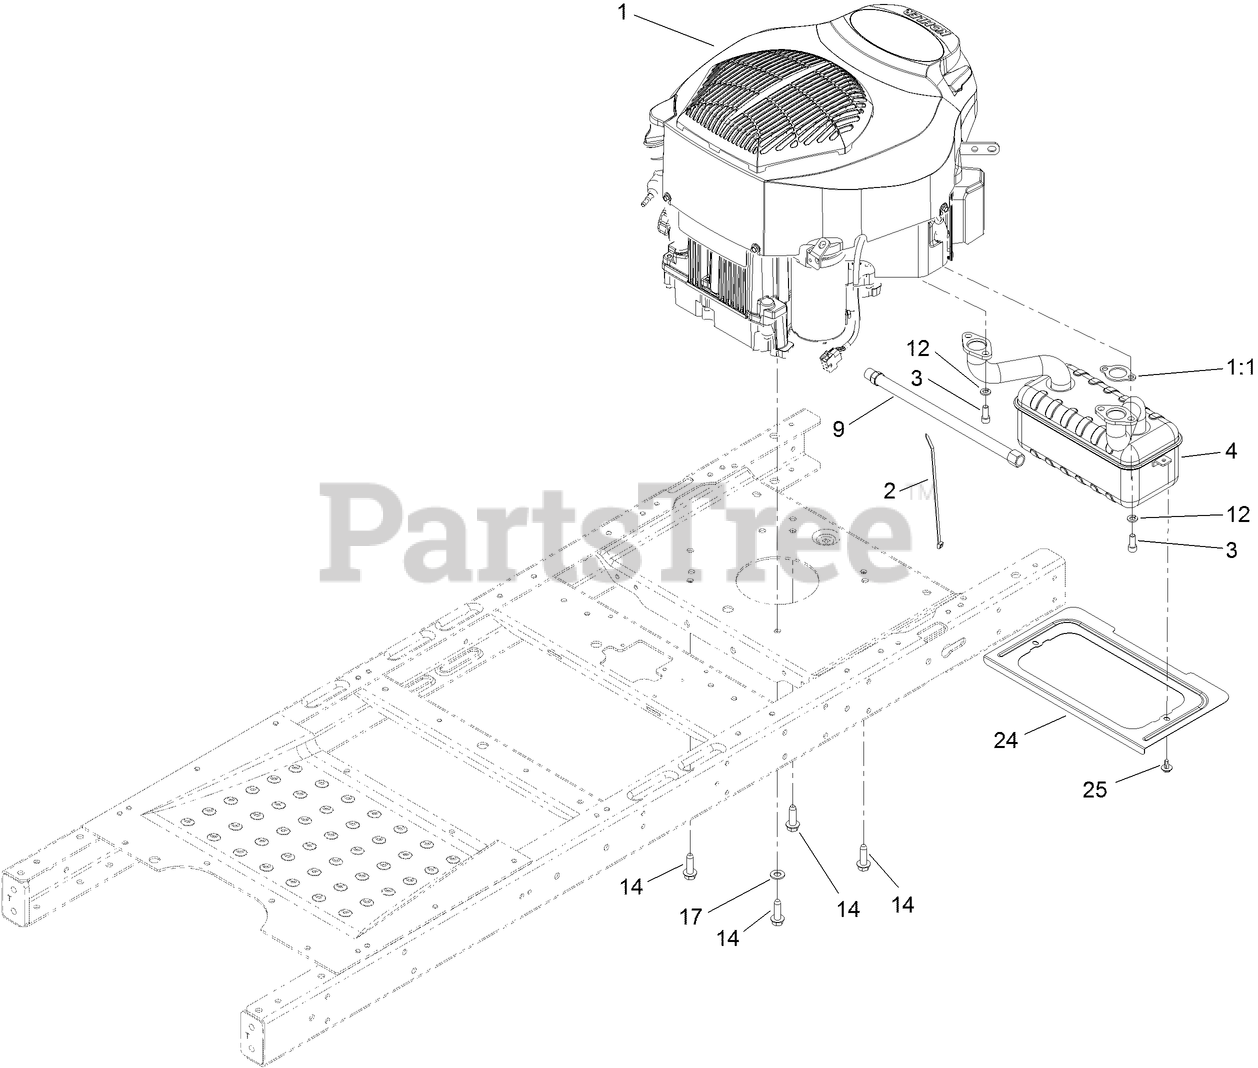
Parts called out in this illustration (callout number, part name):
1	ENGINE-KOHLER 22 HP 7000 SERIES CARB
1:1	GASKET-EXHAUST
2	TIE-CABLE
3	SCREW-HSH
4	MUFFLER
9	HOSE-DRAIN, OIL
12	WASHER-LOCK
14	SCREW-THD
17	WASHER-FLAT
24	SHIELD-HEAT
25	SCREW-HHFTF
